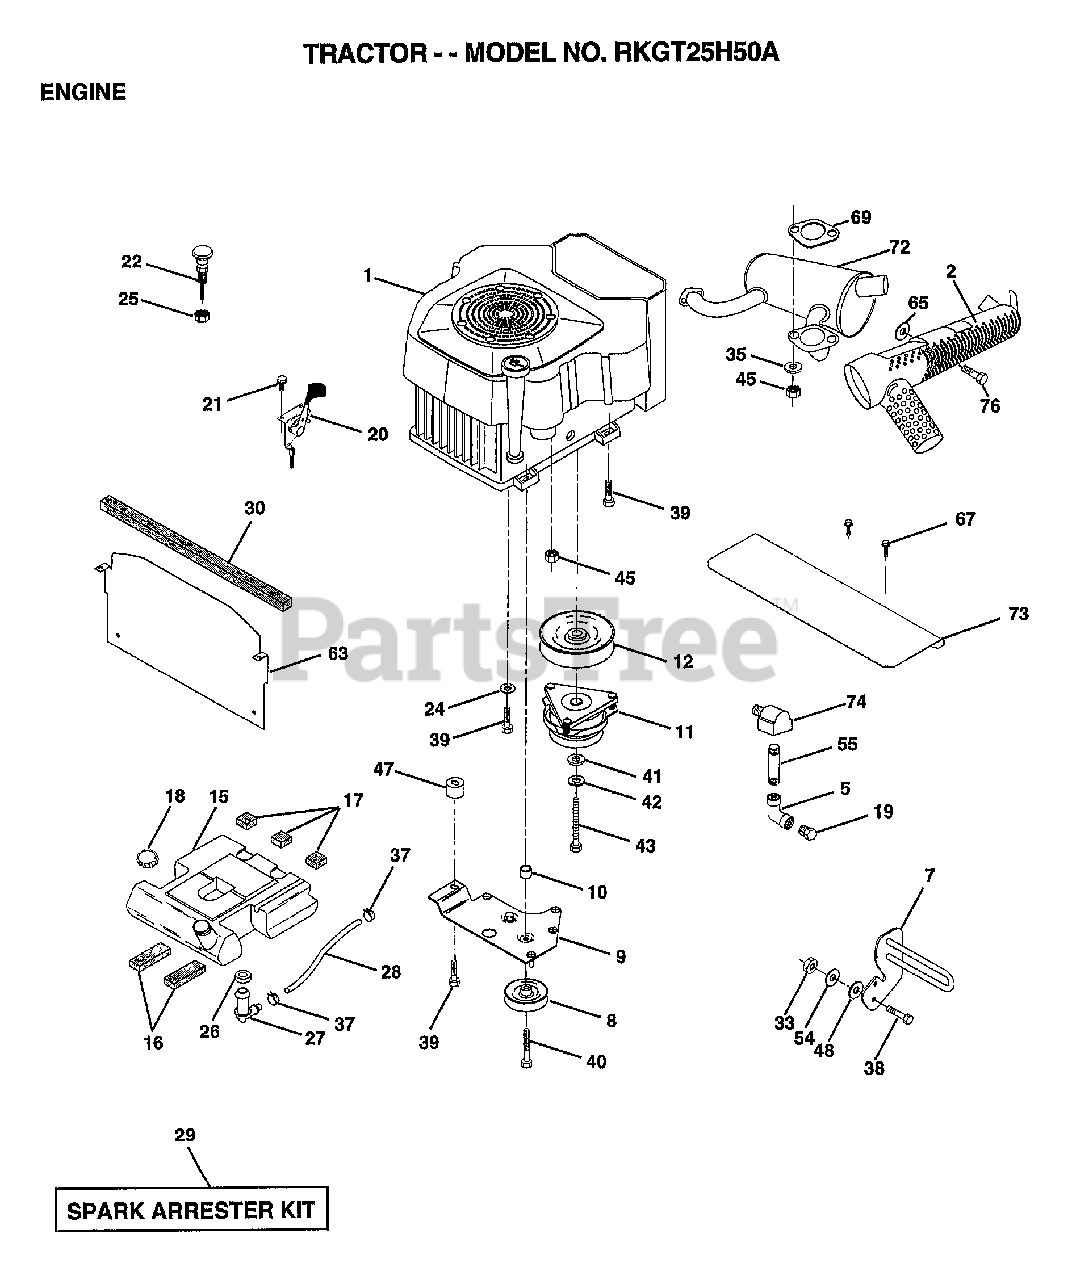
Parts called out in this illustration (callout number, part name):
2	MUFFLER VGT
5	ELBOW
7	GUARD.MUFFLER.ASM
9	KEEPER ASM BELT
10	BUSHING.
12	PULLEY.ENG.CLUTCH
15	TANK FUEL REAR
16	PAD IDLER TI
17	PAD-SPACER LT
18	CAP ASM FUEL
19	PLUG T
20	CONTROL THTL 37
21	SCREW LT
22	CONTROL.CHOKE.37
24	LOCKWASHER
25	"NUT,KEPS 3/8-24IM"
26	BUSHING OUTLET T
27	STEM.TANK.FUEL
29	SPARK ARREST KIT
30	FOAM-STRIP LT
33	NUT
35	WASHER.SPLIT
37	HOSE CLAMP
38	"BOLT,HEX"
39	SCREW.3/8-16X2.25
40	SCREW.TT.3/8-16X4
41	WASHER
42	LOCKWASHER
43	BOLT.7/16-20X4.25
45	NUT FLANGE M8-125
47	SPACER.ENGINE
48	WASHER T
54	WASHER
55	PIPE NIPPLE LT
63	HEAT.SHIELD.VGT.
64	SCREW
65	WASHER
67	SCREW
69	GASKET
72	"MUFFLER,PRE CV25"
73	SHIELD.MUF.KOHLER
74	ELBOW STREET BASS
